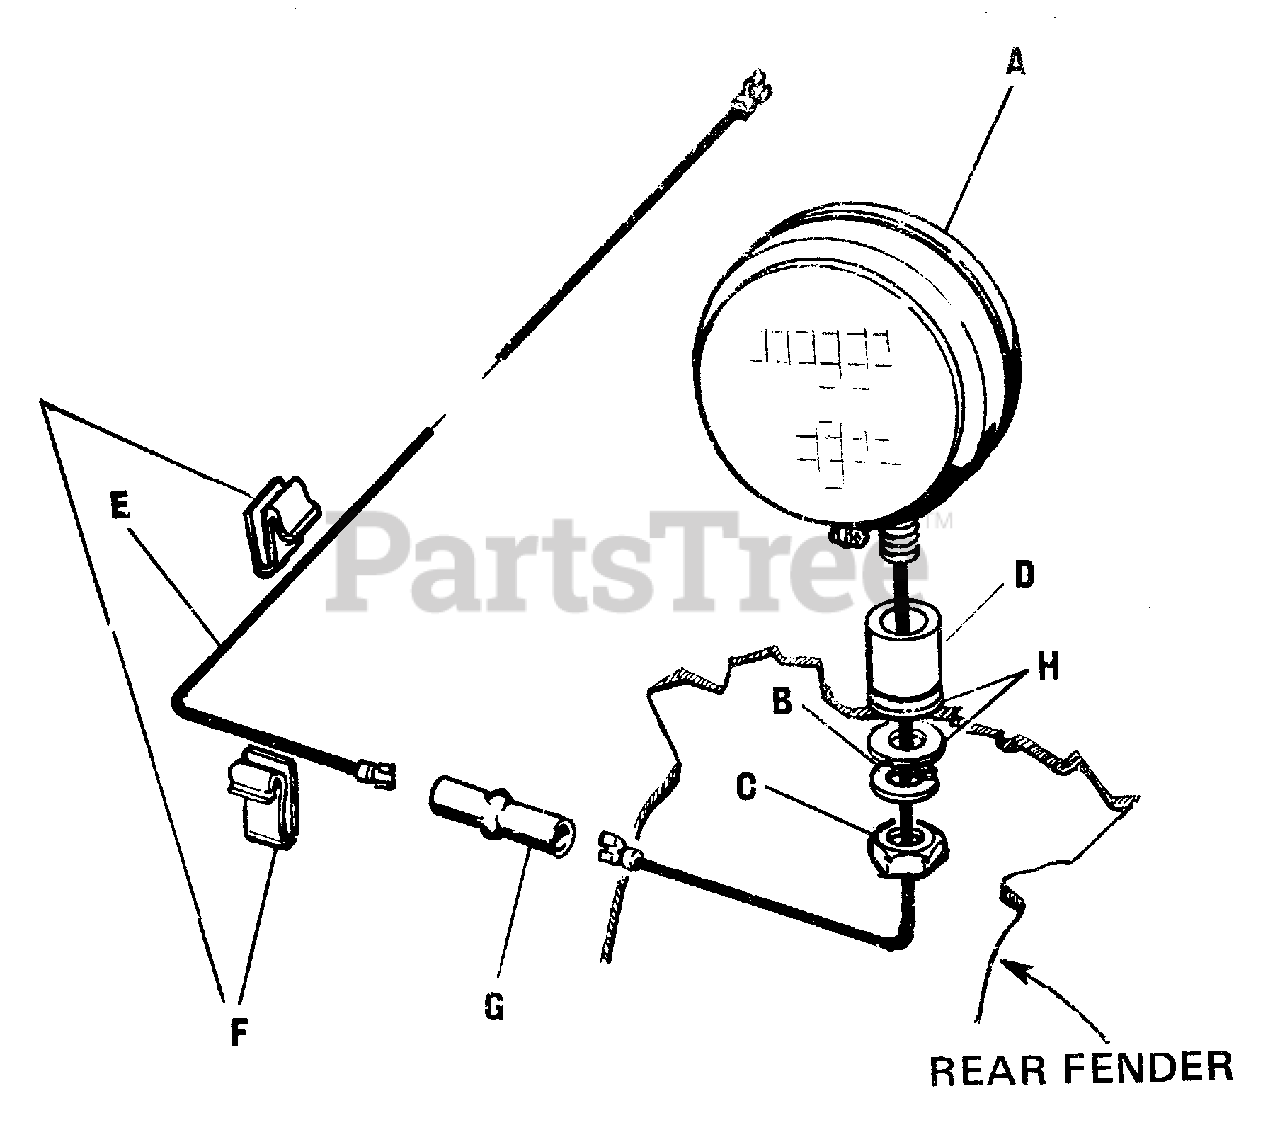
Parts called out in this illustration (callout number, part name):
A	Lamp Assembly
B	Lock Washer, 1/2"
C	Full Hex. Nut, 1/2"-13
E	Wire (to rear lamp)
F	Wire Clip
G	Connector, Line
H	Plain Washer, 7/16"
